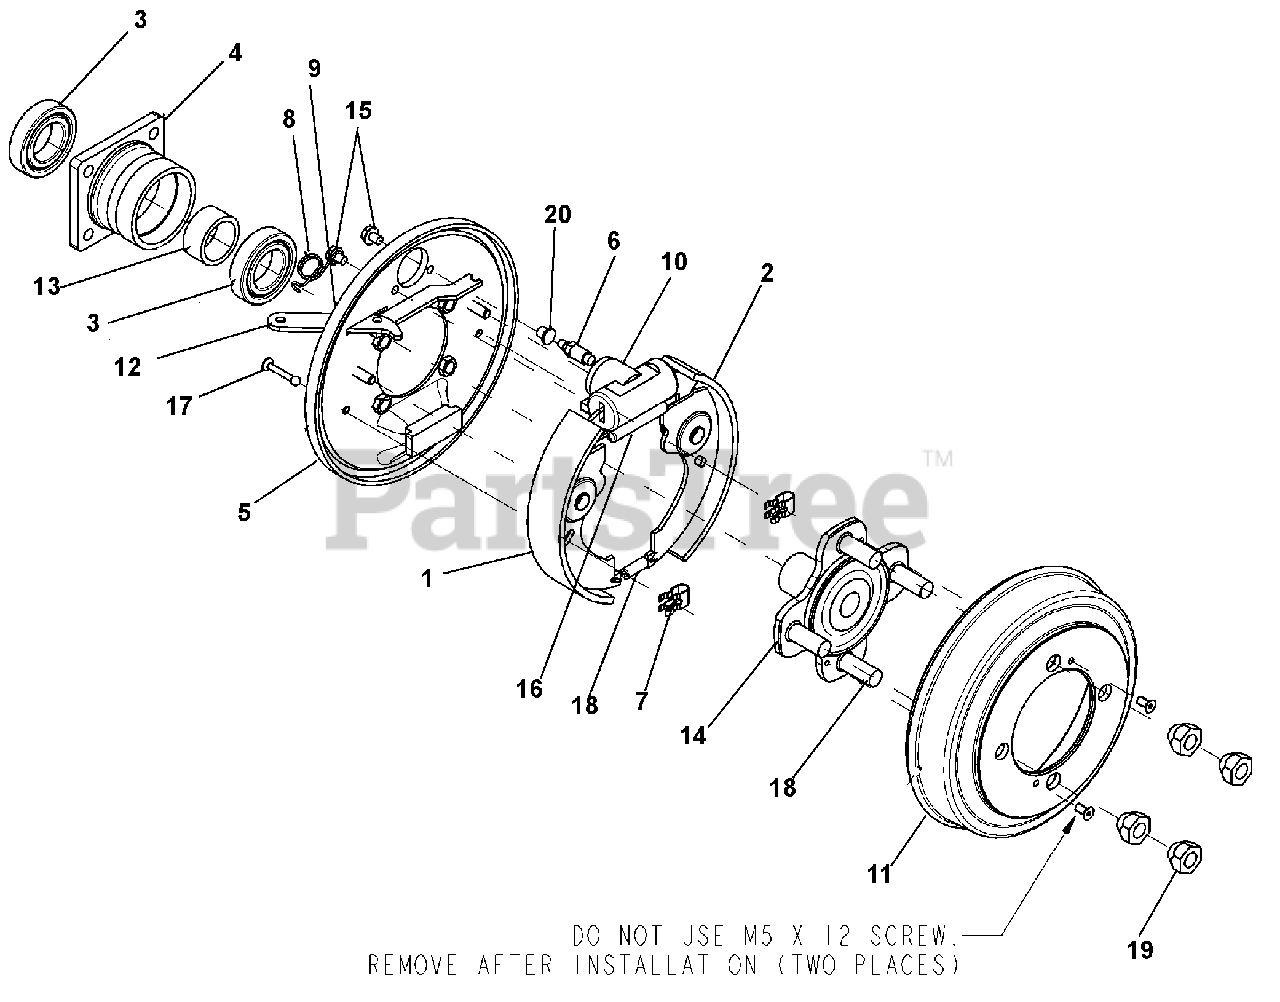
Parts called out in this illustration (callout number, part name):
1	LEFT SHOE
2	RIGHT SHOE
3	BALL BEARING
4	BEARING HOLDER HUB
5	BRAKE SHOE DISC RIGHT HAND
6	BLEEDER SCREW
7	SHOES LOCKING SPRING
8	RIGHT SPRING/HAND BRAKE LEVER
9	LEFT SPRING/HAND BRAKE LEVER
10	HYDRAULIC CYLINDER
11	DRUM
12	RIGHT LEVERS SET
14	BRAKE FLANGE HUB WITH STUDS
15	SCREW M6 X 40
16	UPPER RETURN SPRING
17	SPRING PIN
18	LOWER RETURN SPRING
19	WHEEL NUT .500-20 YZ
20	BLEEDER CAP
F178	BRAKE SHOE DISC LEFT HAND BLEEDER SCREW
F177	LEFT LEVERS SET CMX SPACER
